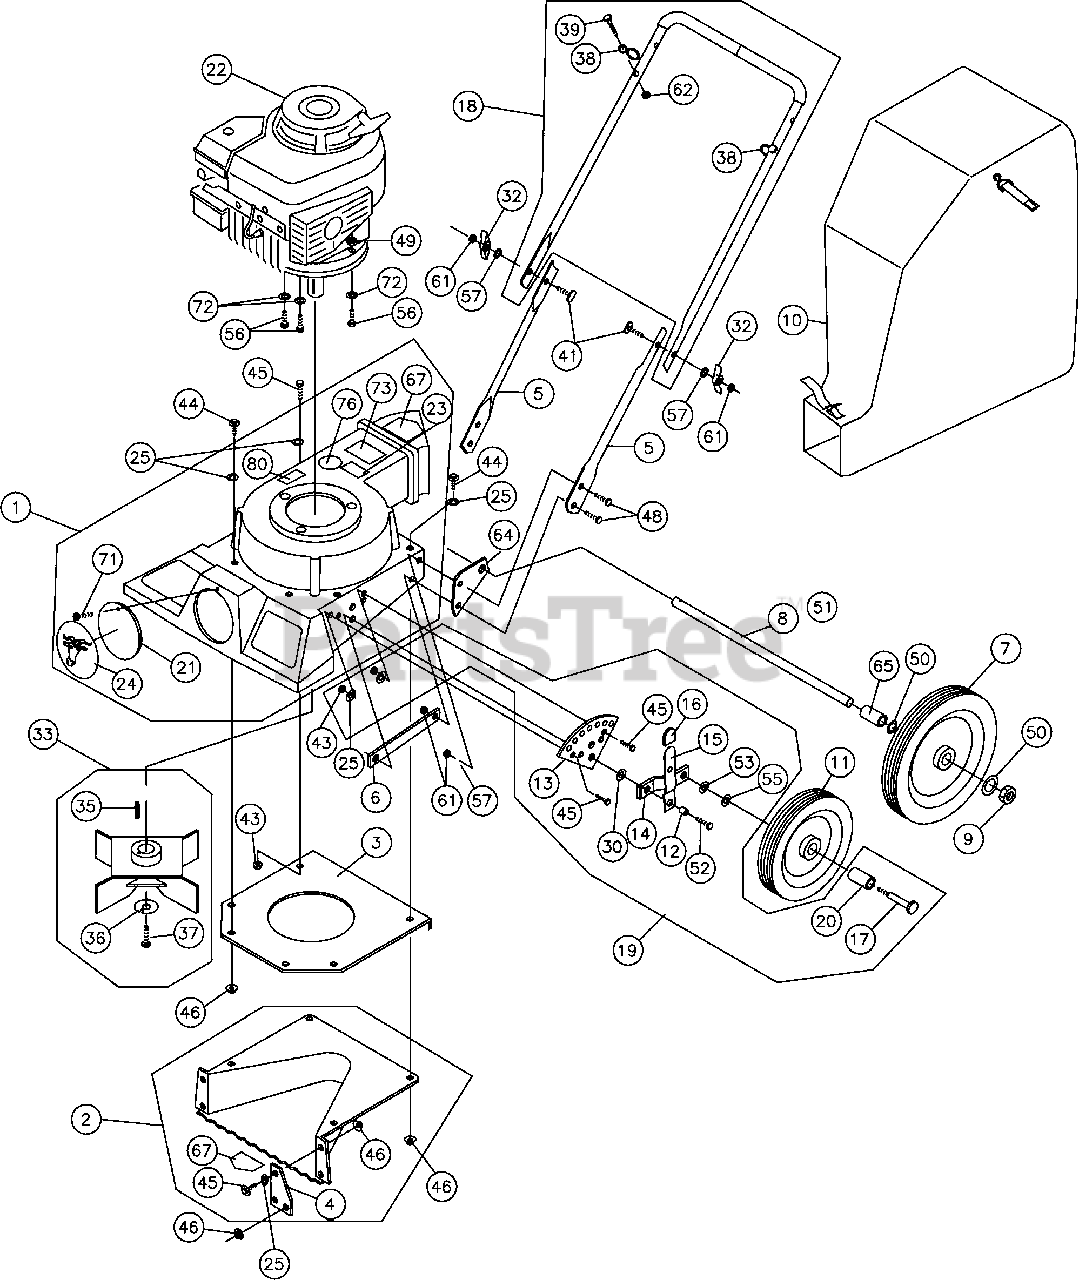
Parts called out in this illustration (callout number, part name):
1	HOUSING ASSY
2	WRAPPER-INTAKE ASSY
3	PLATE MIDDLE INLET
4	PLATE WRAPPER
5	HANDLE LOWER
6	PLATE BACKUP
7	WHEEL REAR 10"
8	AXLE SHAFT
9	NUT LOCK 1/2 -13 THIN HT.
10	BAG DEBRIS
11	WHEEL FRONT 8"
13	PLATE- HT ADJ.
14	AXLE ARM- HT. ADJ.
15	ARM ASSY - HT ADJ.
16	TIP -HT. ADJ.
17	SCREWCAP 3/8-16 X 2 1/2"
18	HANDLE - UPPER ASSY
19	HT. ADJ. ASSY
20	SPACER FRONT WHEEL
22	ENGINE 6.0 H.P. BRIGGS
23	LABEL EAR/EYE BREATHING
24	LABEL LOGO SMALL FRAME
25	WASHER 1/4 SAE
26	SCREWCAP 5/16-16 X 1 1/4
30	WASHER 1/2" FLAT KD WHEEL MTG
32	KNOB-FOLDING HANDLE
33	IMPELLER ASSY
35	KEY-3/16 SQ. X 1 1/4"
36	WASHER LOCK 3/8 S/T MED
37	SCREWCAP 3/8-24 X 1" GR. 8 TORQUE 33-38 FT. LBS (45-52.N.m.)
39	SCREW CAP 1/4-20 X 1 1/4"
41	BOLT CARRIAGE 5/16-18x2 1/4"
43	NUT LOCK 1/4 - 20 HEX ZP
44	SCREWCAP 1/4 -20 X 1"
45	SCREWCAP 1/4-20 X 3/4"
46	NUT LOCK WASHER 1/4-20
48	SCREWCAP 5/16-18 X 1 1/4"
49	NUT LOCK 5/16-18 HEX ZP
50	WASHER FLAT 1/2 SAE (17/32 X 1 1/16 X 3/32)
52	SCREWCAP 3/8-16 X 1 1/2"
53	WASHER LOCK 3/8 S/T MED
55	WASHER FLAT 3/8 SAE (13/32 X 13/16/ X 1/16)
56	SCREW CAP 5/16-18 X 1 1/4
57	WASHER 5/16 SAE (11/32 X 11/16 X 1/16)
61	NUT LOCK 5/16-18
62	NUT LOCK 1/4-20
64	BRACKET AXLE
65	SPACER 1/2 X 5/8
67	LABEL DANGER KEEP HANDS AND FEET AWAY
71	SCREW SELF-TAPPING 10-24 X 1/2
72	WASHER 5/16 FLAT CUT
73	LABEL FLYING DEBRIS
76	LABEL READ MANUAL
80	LABEL MADE IN U.S.A.
